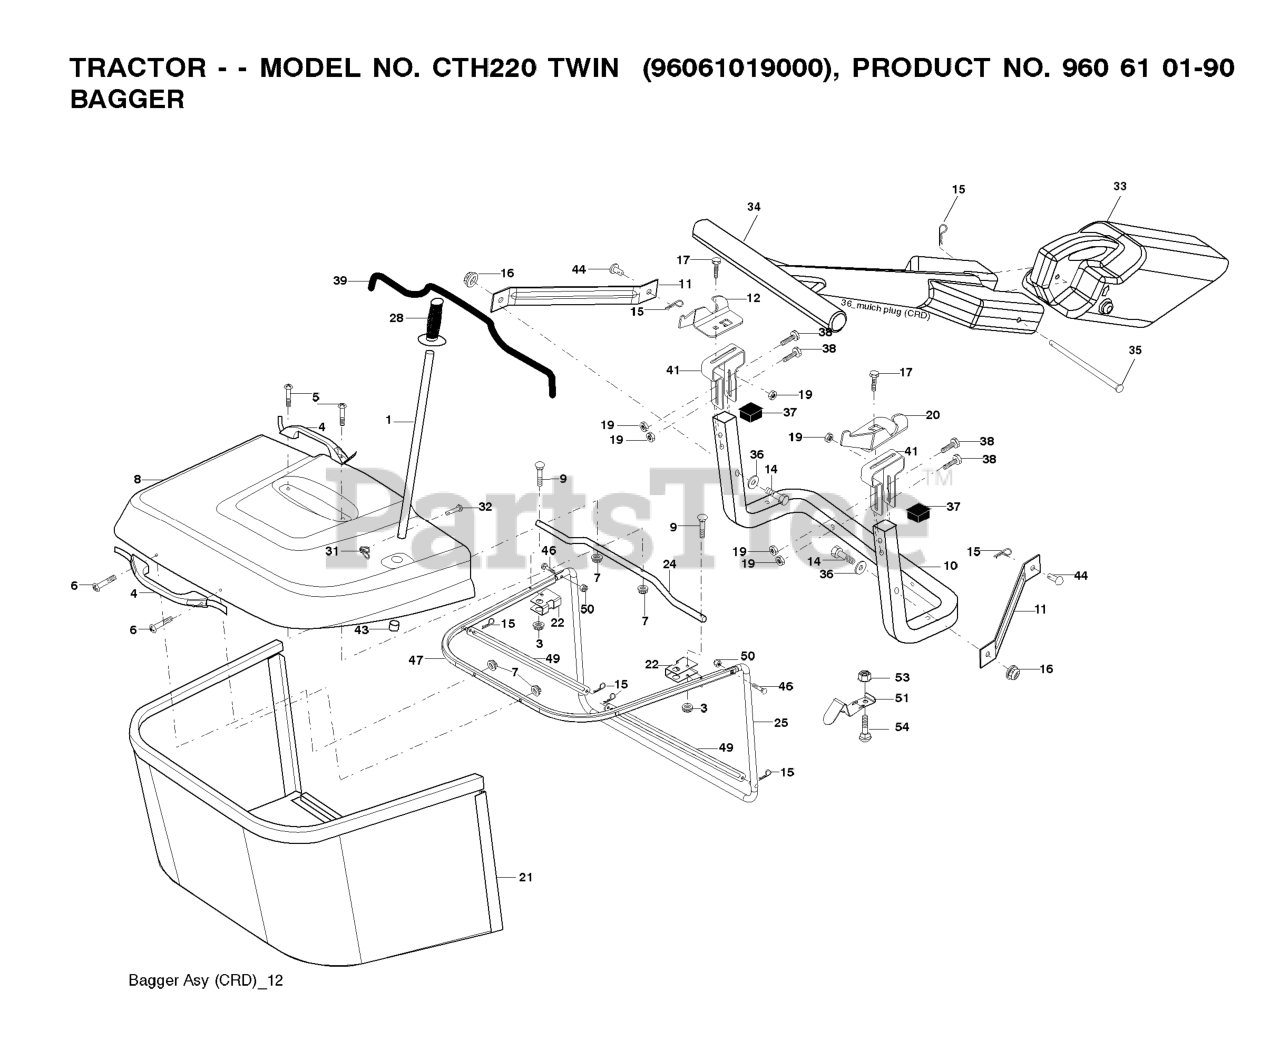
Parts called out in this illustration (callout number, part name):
1	TUBE HANDLE
3	NUT T
4	HANDLE.BAGGER.W/LVRS.BLK.CRD
5	SCREW.PAN.HEAD
6	REPL BY 532 75 00-29
8	COVER.PNT.BGR.CRD.WSLOTS.MS668
9	Bolt Carriage 1/4-20 x 2.25d x Gr.5
10	TUBE
11	BRACKET.SUPPORT.UPPER.BAG.CRD
12	BRKT PIVOT
14	BOLT-HEX EAK
15	RETAINER-SPRNG RB
16	NUT LOCK FLG 3/8-16 UNC
17	RP BOLT 5/16-18 X3/4 ZN/YEL GR
19	NUT LOCK HEX FLANGE 5/16-18
20	BRKT.PIVOT.RH.CRD
21	BAGGER.ASM.CRD.2007
22	BRKT.SIDE.BAG.CRD
24	TUBE.PIVOT.BAG.CRD.BLACK
25	PIPE
28	GRIP.HANDLE.BLACK
31	RETAINER CLIP
32	RIVET,DRILLED
33	MULCH PLUG, CTH150
34	HANDLE.MULCHER.92.CRD (2 2)
36	WASHER
37	Plug Support Bagger CRD
38	BOLT.5/16-18X2.5
39	SEAL.TRIM.37'
41	BRKT.VERT.ADJ.BAGGER.CRD
43	PLUG, TUBING END
46	BOLT.CARRIAGE.5/16-18
47	PIPE
49	ROD
50	NUT.71038.31-18.HEX.NYLOCK
51	LATCH
53	NUT
54	BOLT
